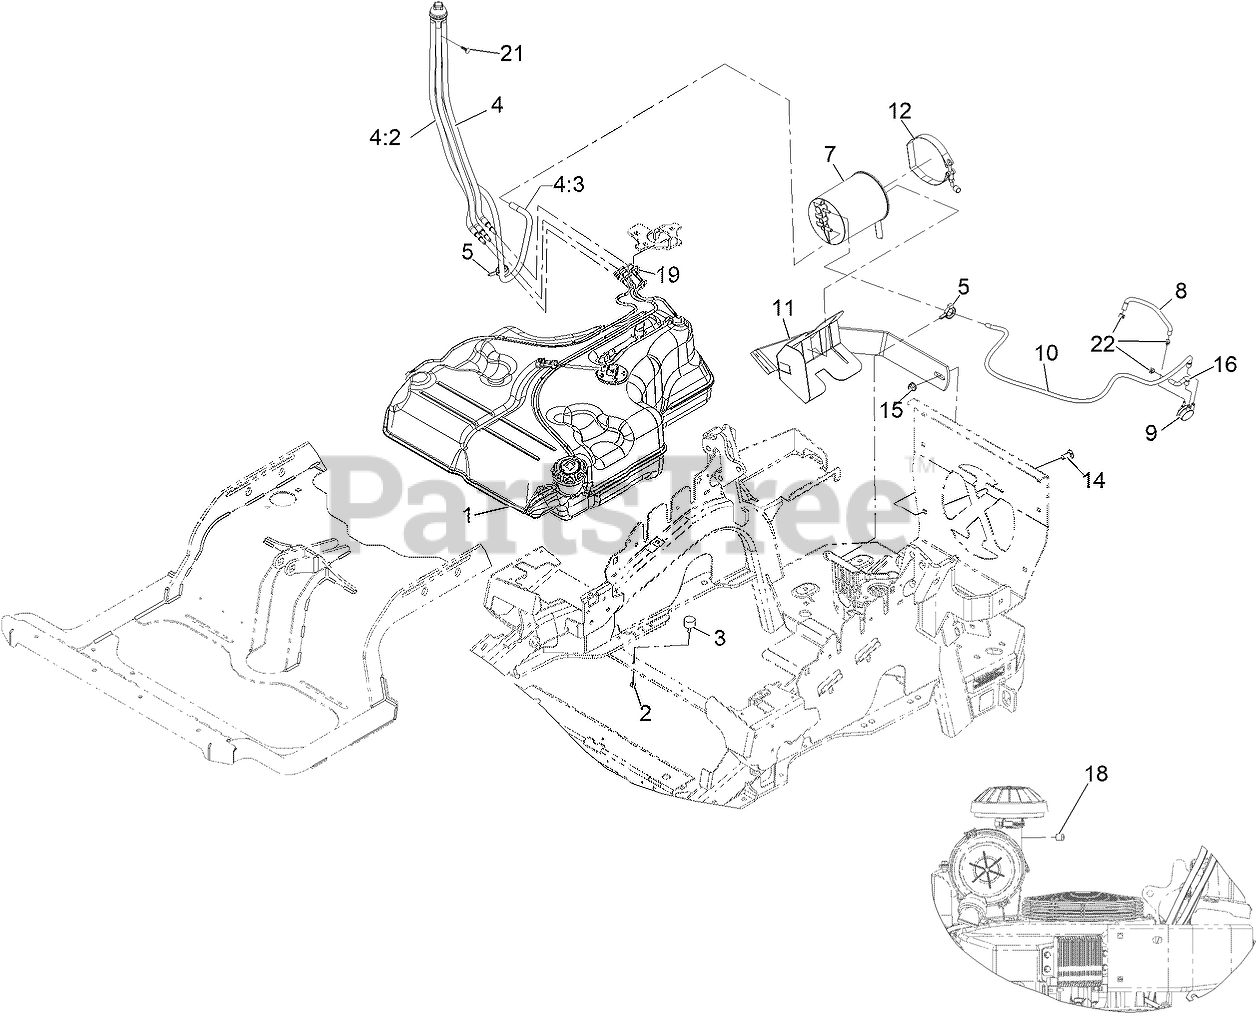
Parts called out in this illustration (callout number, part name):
1	FUEL TANK ASM
2	NUT-JAM
4	FUEL MANIFOLD VENT ASM
4:2	HOSE-FUEL
4:3	HOSE-FUEL
5	CLAMP-HOSE
7	CANISTER-CARBON, 1200CC
8	HOSE-VENT,FORMED
9	VALVE-CONTROL, VACUUM
10	HOSE,VENT,FORMED
11	MOUNT-CANISTER
12	CLAMP, T-BOLT
14	SCREW-CARR
15	NUT-HF, NI
16	HOSE-VENT, FORMED
18	PLUG-PORT
19	RETAINER-LINE, VAPOR
21	PLUG-PLASTIC
22	Clamp - Hose
